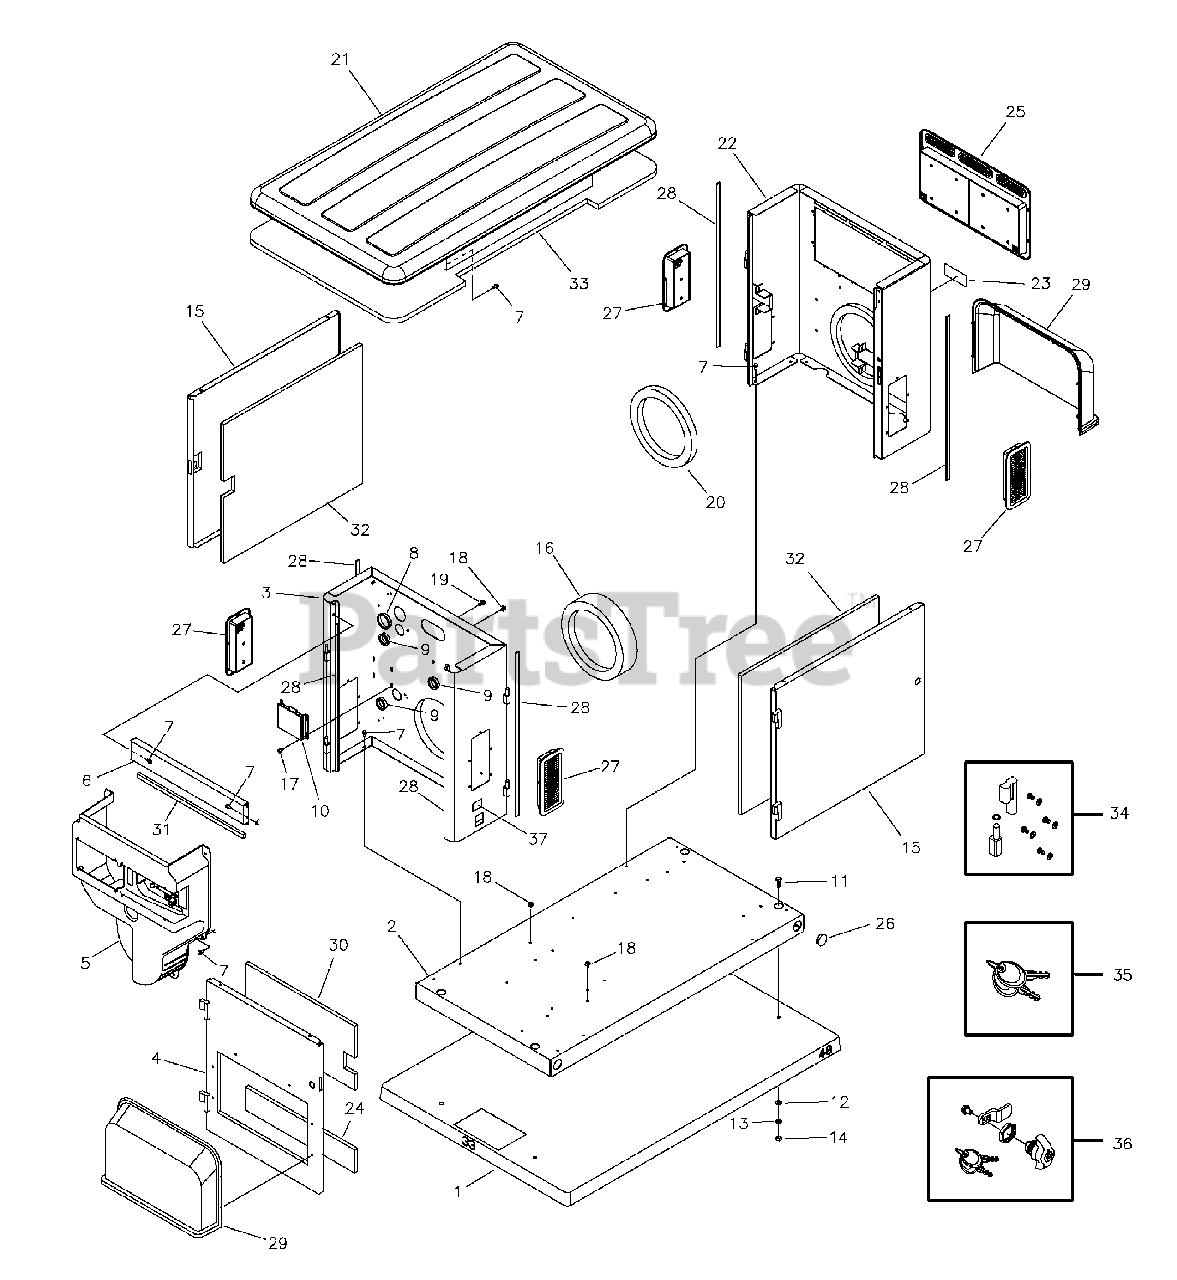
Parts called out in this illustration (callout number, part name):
2	BASE
3	BULKHEAD ASSEMBLY, Engine
6	SUPPORT RAIL ASSEMBLY
7	CAPSCREW, Hex Head, Trilobular, 1/4-20 x 1/2
8	BUSHING, Snap, 2"
9	Bushing, Snap, 1-1/2"
10	Regulator, Voltage
11	*CAPSCREW, Hex Head, 3/8 - 16 x 1
12	*WASHER, Flat, 3/8 - M10
13	*WASHER, Lock, 3/8
14	*NUT, 3/8-16
16	SEAL, Foam
17	CAPSCREW, Hex Head, Trilobular, #8-32 x 1/2
18	MOUNT, Tie Wrap
20	SEAL, Foam
22	BULKHEAD ASSEMBLY, Alternator End
23	DECAL, Caution Hot Muffler
24	INSULATION, Engine Door, Bottom
29	COVER, Air Intake Engine
30	INSULATION, Engine Door, Top
32	INSULATION, Front/Rear Door
33	INSULATION, Roof
34	KIT, Door, Hinge
36	KIT, Door Latch
